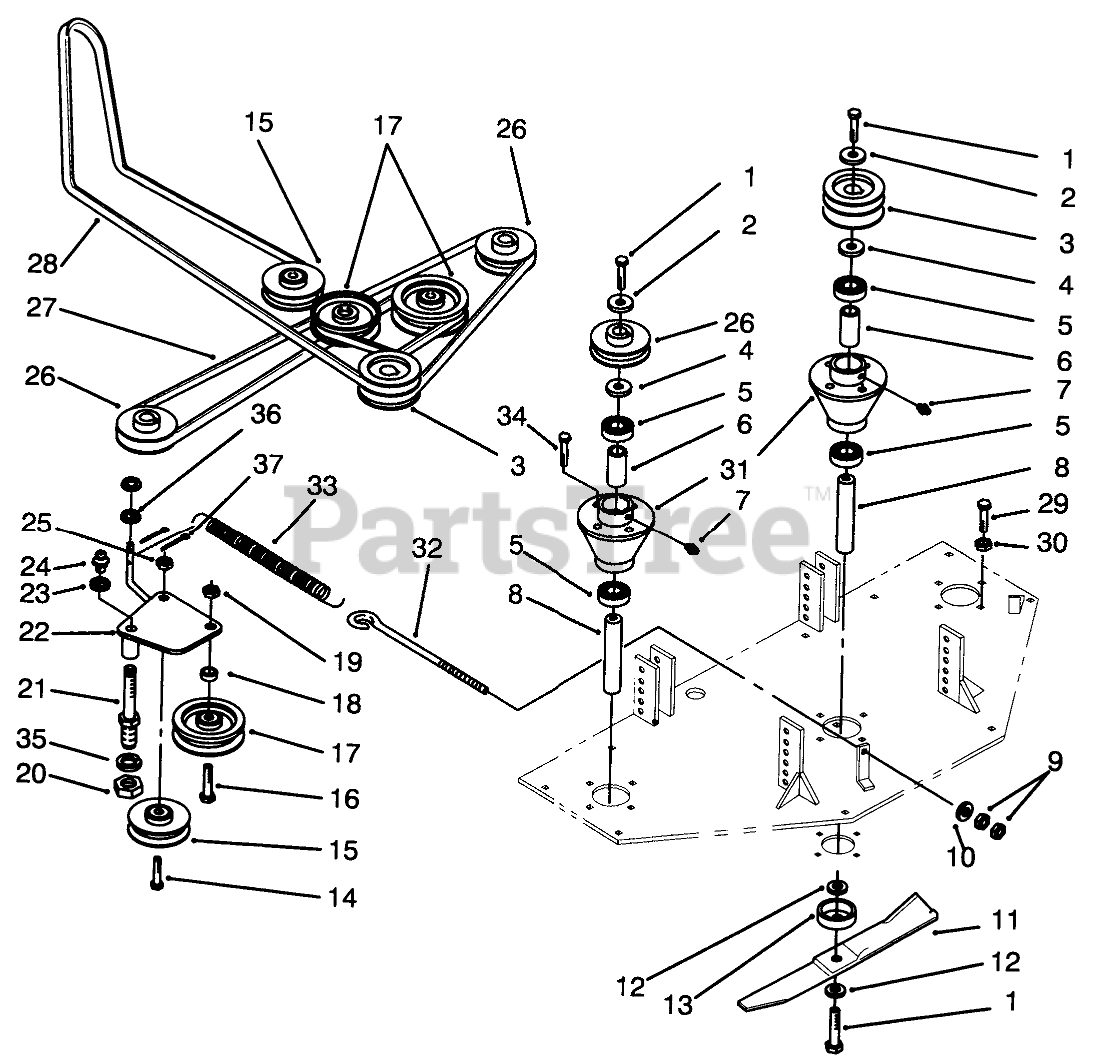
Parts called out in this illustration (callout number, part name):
2	WASHER-SPECIAL
3	PULLEY-CENTER
4	SPACER
5	BEARING-BALL
7	FITTING-GREASE
8	SHAFT-SPINDLE
9	NUT-HEX
10	WASHER-PLAIN
11	MOWER BLADE 17"
12	WASHER-SPECIAL
13	CUP-SPINDLE
14	SCREW-HH
15	PULLEY-IDLER
16	SCREW-HH
17	PULLEY FLAT B
18	SPACER
19	NUT-LOCK, NI
20	NUT-LOCK, NI
21	SHAFT-BELT TEN PI
22	WLDMT-IDLER PLATE R
23	RETAINING RING
24	FITTING-GREASE, 90 DEG
25	NUT-LOCK, NI
26	PULLEY-OUTER
27	BELT-V
28	BELT-50" MOW DR 724Z
29	SCREW-HH
30	NUT-JAM
31	HOUSING-SPINDLE
32	EYE-BOLT
33	Spring-Idler
34	SCREW-HH, LOCK
35	WASHER
36	WASHER
37	PIN-COTTER
